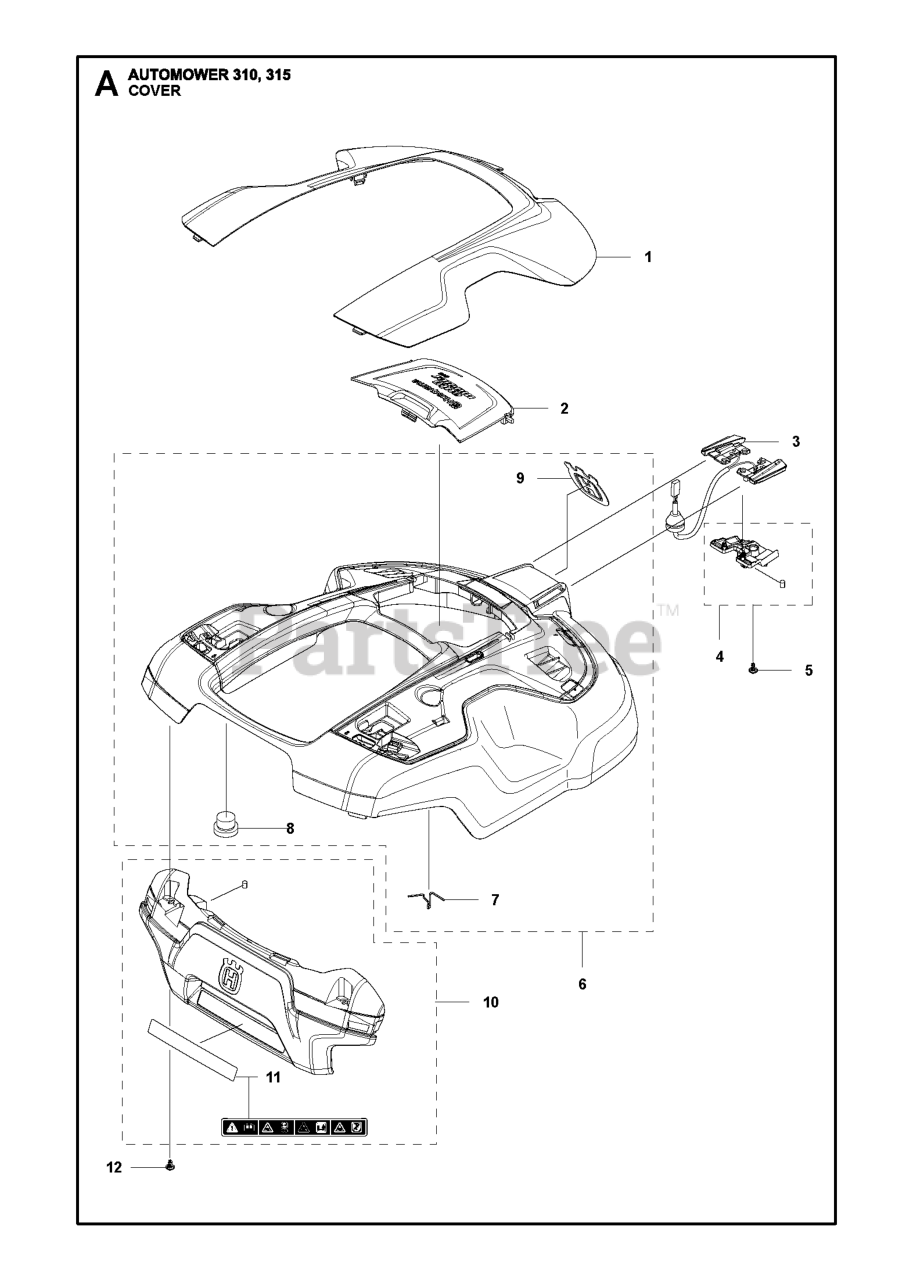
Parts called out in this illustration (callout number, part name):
1	MAIN CABLE
4	DIAGNOSTIC TOOL KIT
5	WIRING ASSY
